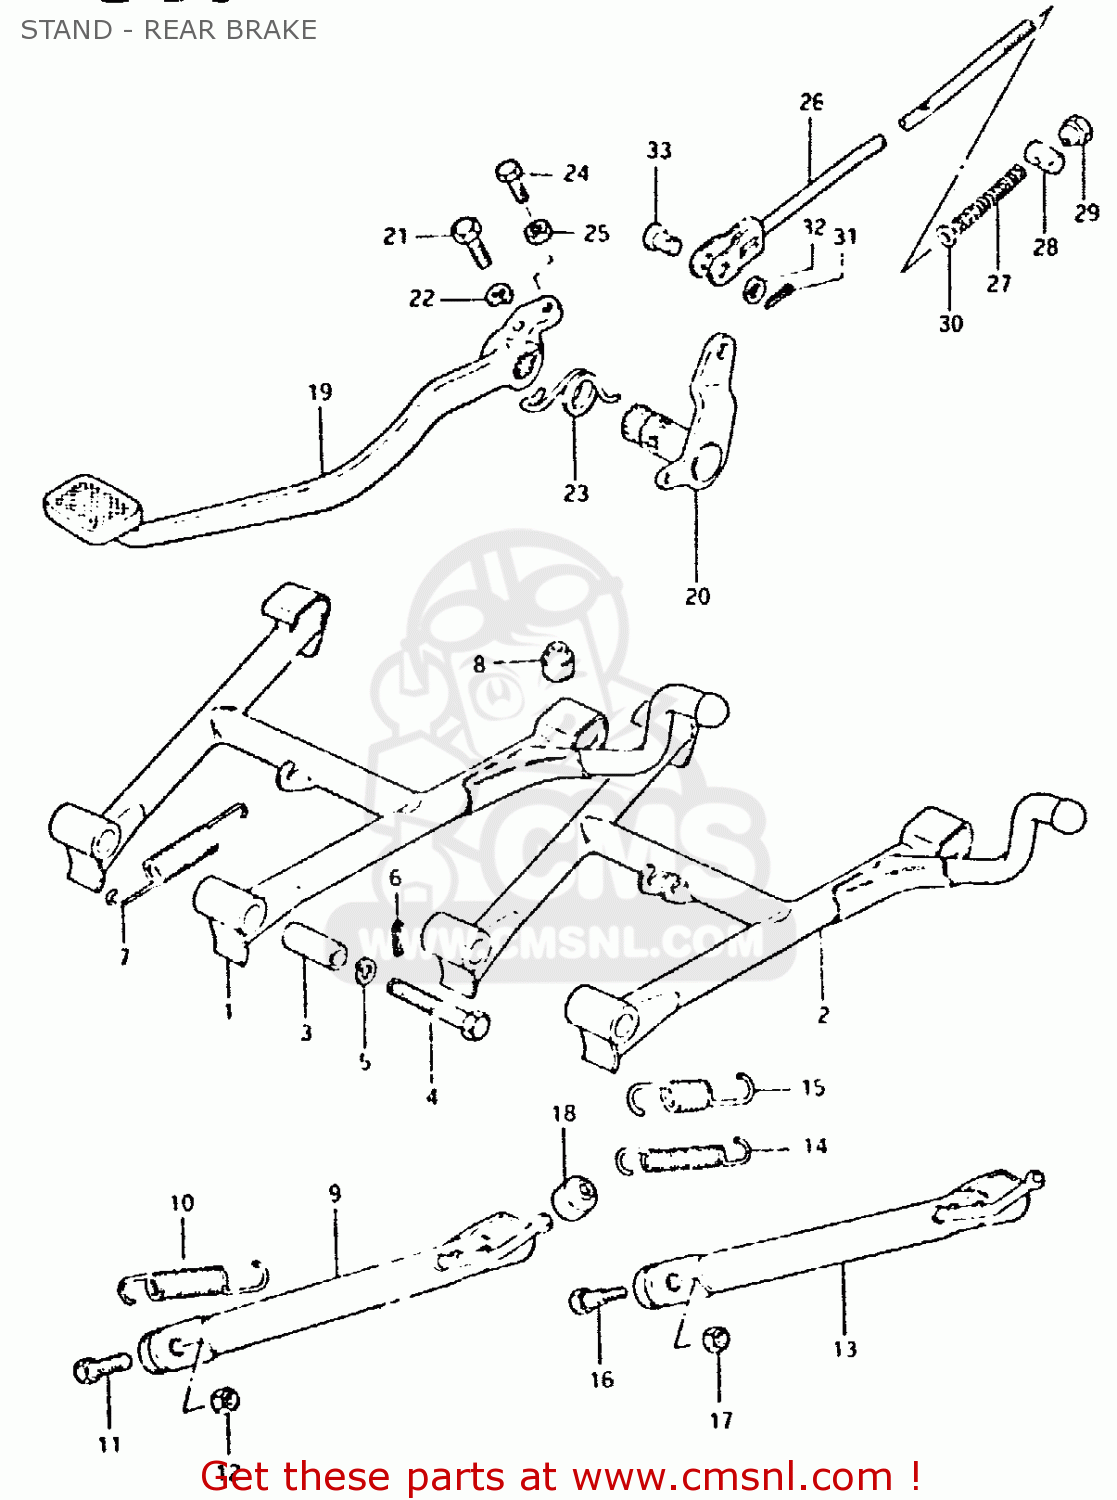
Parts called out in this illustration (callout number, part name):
1	STAND,CENTER
3	SPACER(10X16X38.8)
4	BOLT
5	LOCK WASHER
6	CLIP
7	SPRING
8	CUSHION
9	STAND,SIDE
10	SPRING
11	BOLT(10X30)
12	NUT
18	CUSHION
19	PEDAL,BRAKE
20	ARM,BRAKE PEDAL ROD
21	BOLT
22	LOCK WASHER
23	SPRING
24	BOLT
25	NUT
26	ROD ASSEMBLY,REAR BRAKE
27	SPRING
28	PIN
29	NUT
30	WASHER
31	PIN(L:13.5)
32	WASHER
33	PIN 20X20
